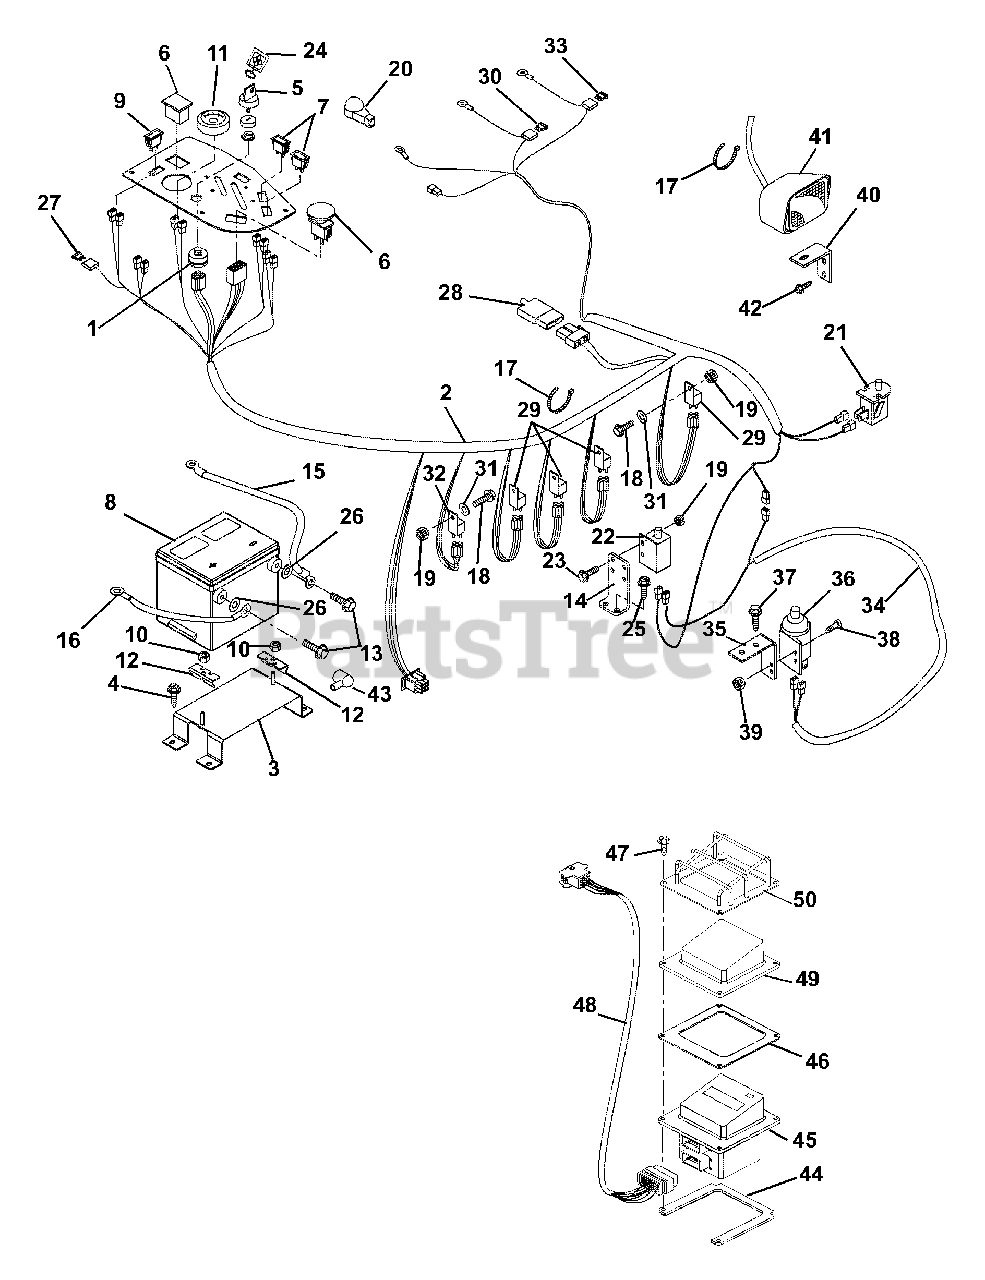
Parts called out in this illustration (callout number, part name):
1	SWITCH, IGNITION (DIESEL)
2	HARNESS, HORZ. L/C(DIESEL)
3	WMT, BATTERY SUPPORT
4	@SCR-TAP .38-16X.75 HWH TR YWZ
5	KEY, W/ SHIELD
6	PLUG, HOUR METER
7	LIGHT,INDICATOR
8	BATTERY, GROUP 70 450 CCA 35 A
9	SWITCH, 2 POLE/ROCKER
10	@NUT-LK-TOP-FLG .31-18 YWZC
11	GAUGE, TEMPERATURE
12	BRKT, BATTERY HOLD-DOWN
13	BATT TERMINAL SCREW
14	MOUNT, SAFETY SWITCH
15	CABLE, POS BATT 4 GA X 45
16	CABLE, NEGATIVE BATTERY 49.00
17	CABLE TIE LG 5-1/2
18	@SCR-MCH 10-24X.75 HWH YWZC
19	@NUT-LK-NYL 10-24 W/INSRT YWZC
20	BOOT, EYELET TERMINAL
21	SWITCH- SNAP MTG N.O.
22	SWITCH- SINGLE POLE N.O.
23	@SCR-MCH 10-24X.75 HWH YWZC
24	KEY CHAIN
25	@SCR-TAP .25-20X.50 HWH TR YWZ
26	@WSHR-FL-STL.38X.875X.083 YWZC
27	FUSE, 15 AMP.
28	DIODE, CONNECTOR SHELL
29	RELAY
30	FUSE, 30 AMP.
31	@WSHR-FL-STL.250X.56X.049 YWZC
32	Pre-Heat Timer
33	FUSE, 50 AMP (MAXI FUSE)
34	HARNESS, WIRE ADAPTER CE
35	MOUNT - SWITCH
36	SWITCH-SINGLE POLE N.O.W/COVER
37	@SCR-TAP .31-18X.50 HWH TR YWZ
38	@SCR-MCH 10-24X.75 HWH YWZC
39	@NUT-LK-NYL 10-24 W/INSRT YWZC
40	BRACKET, HEADLIGHT MTG
41	HEADLIGHT
42	@SCR-TAP .38-16X.50 HWH TR YWZ
43	BOOT, EYELET TERMINAL
44	SPACER, ENCLOSURE MTG. (BTM)
45	ASSY, EYE-Q
46	GASKET-EYE Q
47	SCR-MCH 10-24X1.0 SL PAN BLACK
48	HARNESS - EYE-Q
49	GUARD, ELEMENT
50	GUARD, VINYL EYE-Q
